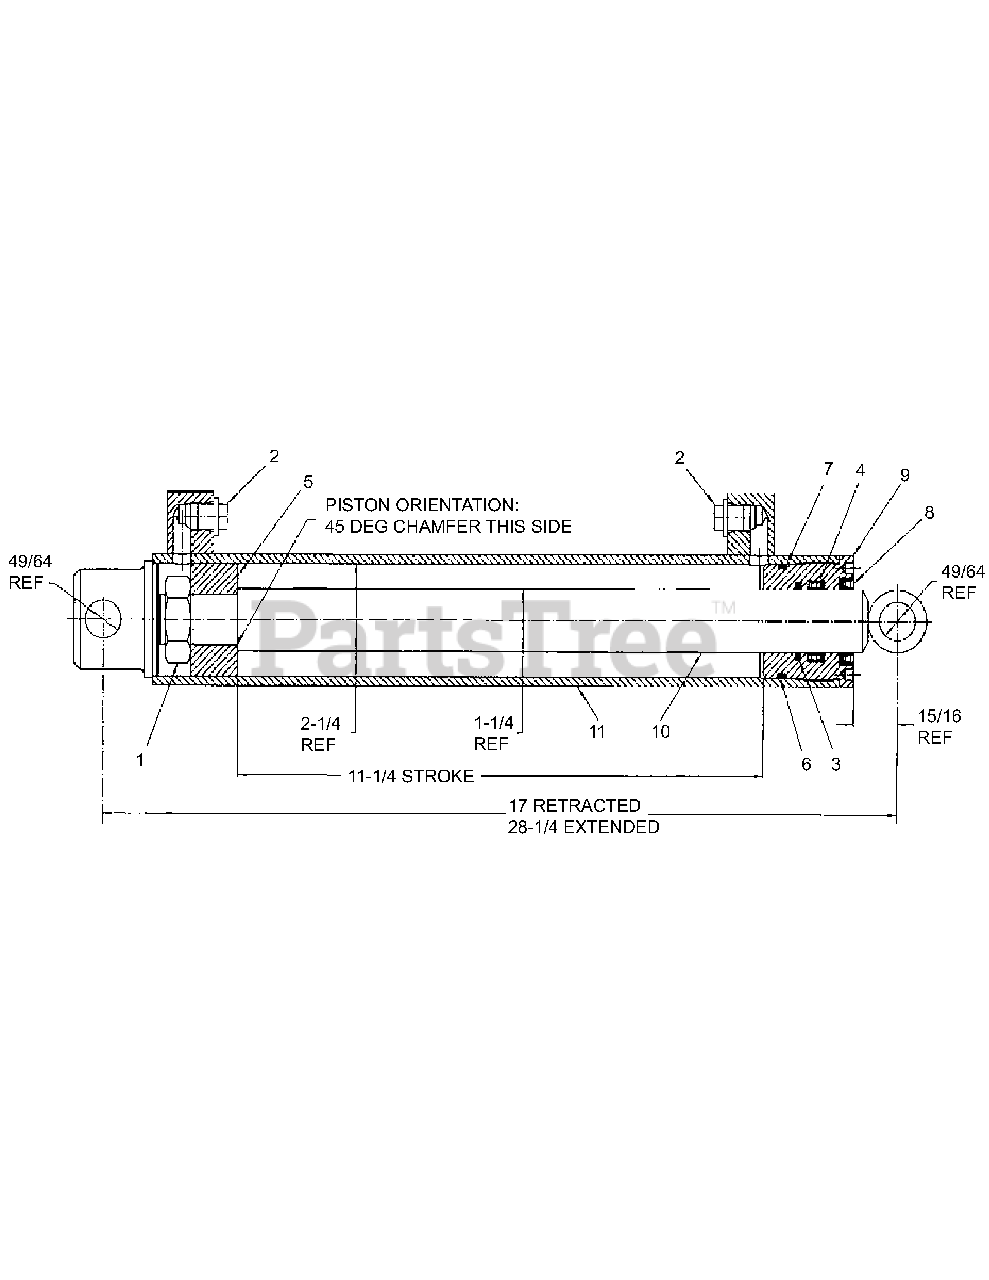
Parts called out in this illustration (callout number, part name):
1	Nut, 1" Lock
3	Step Seal*
4	U-Cup Seal*
6	O-Ring*
7	Back-Up Ring*
8	Rod Wiper*
9	Threaded Gland
10	Piston Rod Weldment
11	Cylinder Tube Weldment
